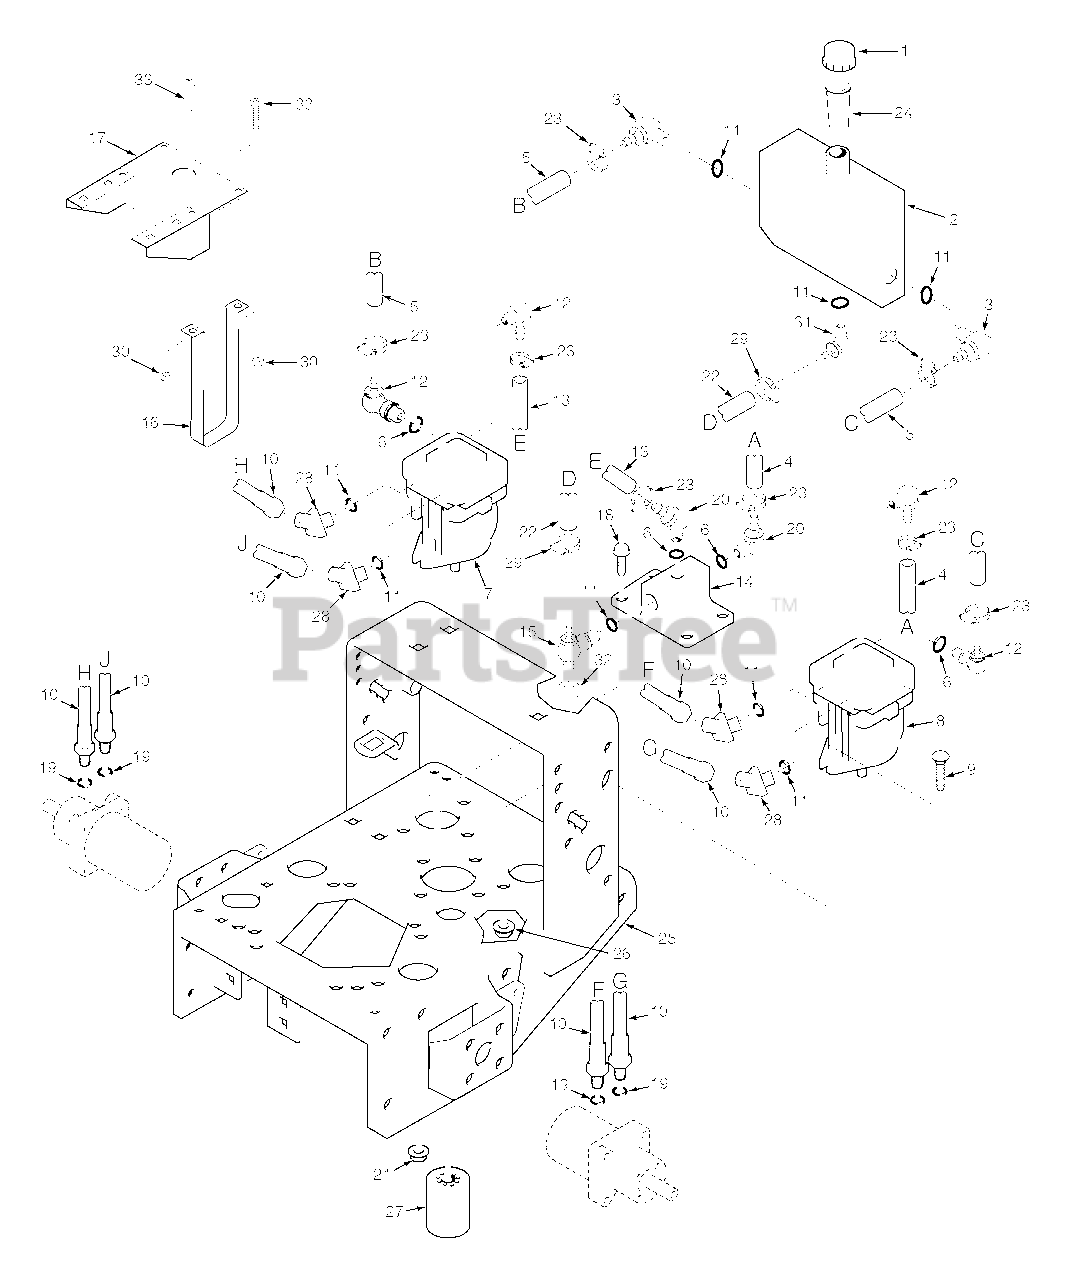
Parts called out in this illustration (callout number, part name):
1	Cap, Oil Reservoir
2	Oil Reservoir (With Fittings)
3	Elbow, 9/16 O-Ring x 3/8 Hose
4	Hose, 3/8" ID - 10-1/4" Long (Order By The Inch)
5	Hose, 3/8" ID - 7" Long (Order By The Inch)
6	O-Ring
7	Pump, PG-1JQQ-DY1X-XXXX (R.H.)
8	Pump, PG-1GQQ-DY1X-XXXX (L.H.)
9	Bolt, Carriage, 3/8-16 x 1.25"
10	Hose, Pump to Wheel Motor
11	O-Ring
12	Elbow, 7/16-20 O-Ring x 3/8 Hose
13	Hose, 3/8" ID - 11" Long (Order By The Inch)
14	Oil Filter Base
15	Tee, 3/8 O-Ring x JIC x 1/2 Hose
16	Strap, Hydraulic Tank
17	Bracket, Hydraulic Tank
18	Capscrew, 5/16-18 x .75" Serr. Flange
19	O-Ring
20	Elbow, 9/16 O-Ring x 3/8 Hose
21	Nut, 5/16-18 Serr. Flange
22	Hose, Formed 1/2" ID
23	Clamp, .69 max dia.
24	Tube, Filler Neck
25	Engine Deck (16" Wide) W/Decals
26	Nut, 3/8-16 Serr. Flange
27	Oil Filter
28	Elbow, 45 Deg.-3/4-16 JIC Male x Male 3/4-16 O-Ring
29	Clamp, .87 max di.
30	Nut, 1/4-20
31	Elbow, 3/4-16 O-Ring x 1/2 Hose
32	Cap, 3/4-16
33	Screw, 1/4-20 x 2.0" Round Head Phillips
